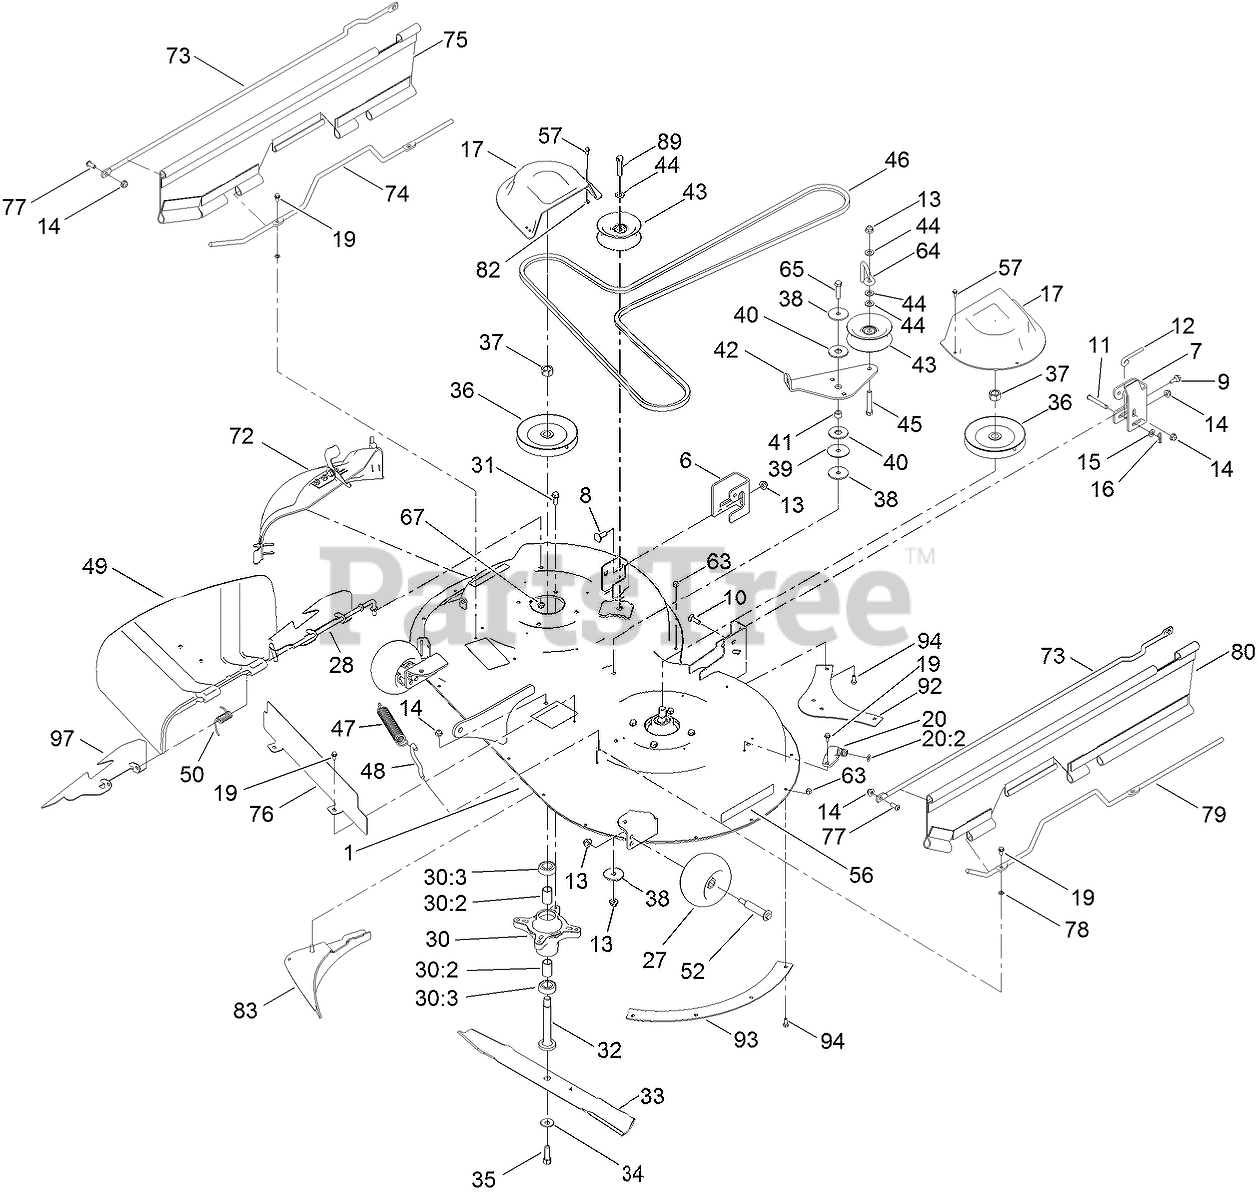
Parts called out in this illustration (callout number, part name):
1	42 INCH DECK AND DECAL ASM
6	BRACKET-HANGER, RH
7	BRACKET-HANGER, LH
8	BOLT-CARR
9	SCREW-SHOULDER,HWH
10	SCREW-CARR
11	PIN-CLEVIS
12	ROD-LEVEL, DECK
13	NUT-HF, NI
14	NUT-HF, NI
15	WASHER-PLAIN
16	PIN-COTTER
17	COVER-BELT
19	SCREW-HWH
20	FITTING-WASHOUT
20:2	O-RING
27	ROLLER-SCALP, ANTI
28	ROD-PIVOT
30	SPINDLE ASM
30:2	SPACER
30:3	BEARING-BALL
31	SCREW-TAPTITE
32	SHAFT-SPINDLE
33	BLADE-MULCH
34	WASHER-BELLEVILLE
35	SCREW-HH
36	PULLEY
37	NUT-HEX
38	WASHER-REBOUND
39	WASHER
40	WASHER-FRICTION, COMPOSITE
41	SPACER
42	ARM-IDLER
43	PULLEY-IDLER, FLAT
44	WASHER-FLAT
45	SCREW-HH
46	V-BELT
47	SPRING-EXTENSION
48	HOOK-RETURN, SPRING
49	DEFLECTOR
50	SPRING-TORSION
52	BOLT-SHOULDER
56	DECAL-RECYCLER
57	SCREW-TAPTITE
63	NUT-LOCK, NI
64	GUIDE-IDLER, BELT
65	SCREW-HH
72	42 INCH MULCH PLUG ASM
73	ROD-SUPPORT, UPPER
74	ROD-SUPPORT, LOWER (RH)
75	RIGHT GUARD ASM
76	SHIELD-FROUNT
77	SCREW-HSBH
78	NUT-RETAINING
79	ROD-SUPPORT, LOWER (LH)
80	LEFT GUARD ASM
82	NUT-RETAINING
83	BAFFLE-CLIPPING
89	SCREW-HH
92	BAFFLE-BLOWOUT, REAR
93	BAFFLE-BLOWOUT, SIDE
94	SCREW-HH
97	DEFLECTOR-INSERT
